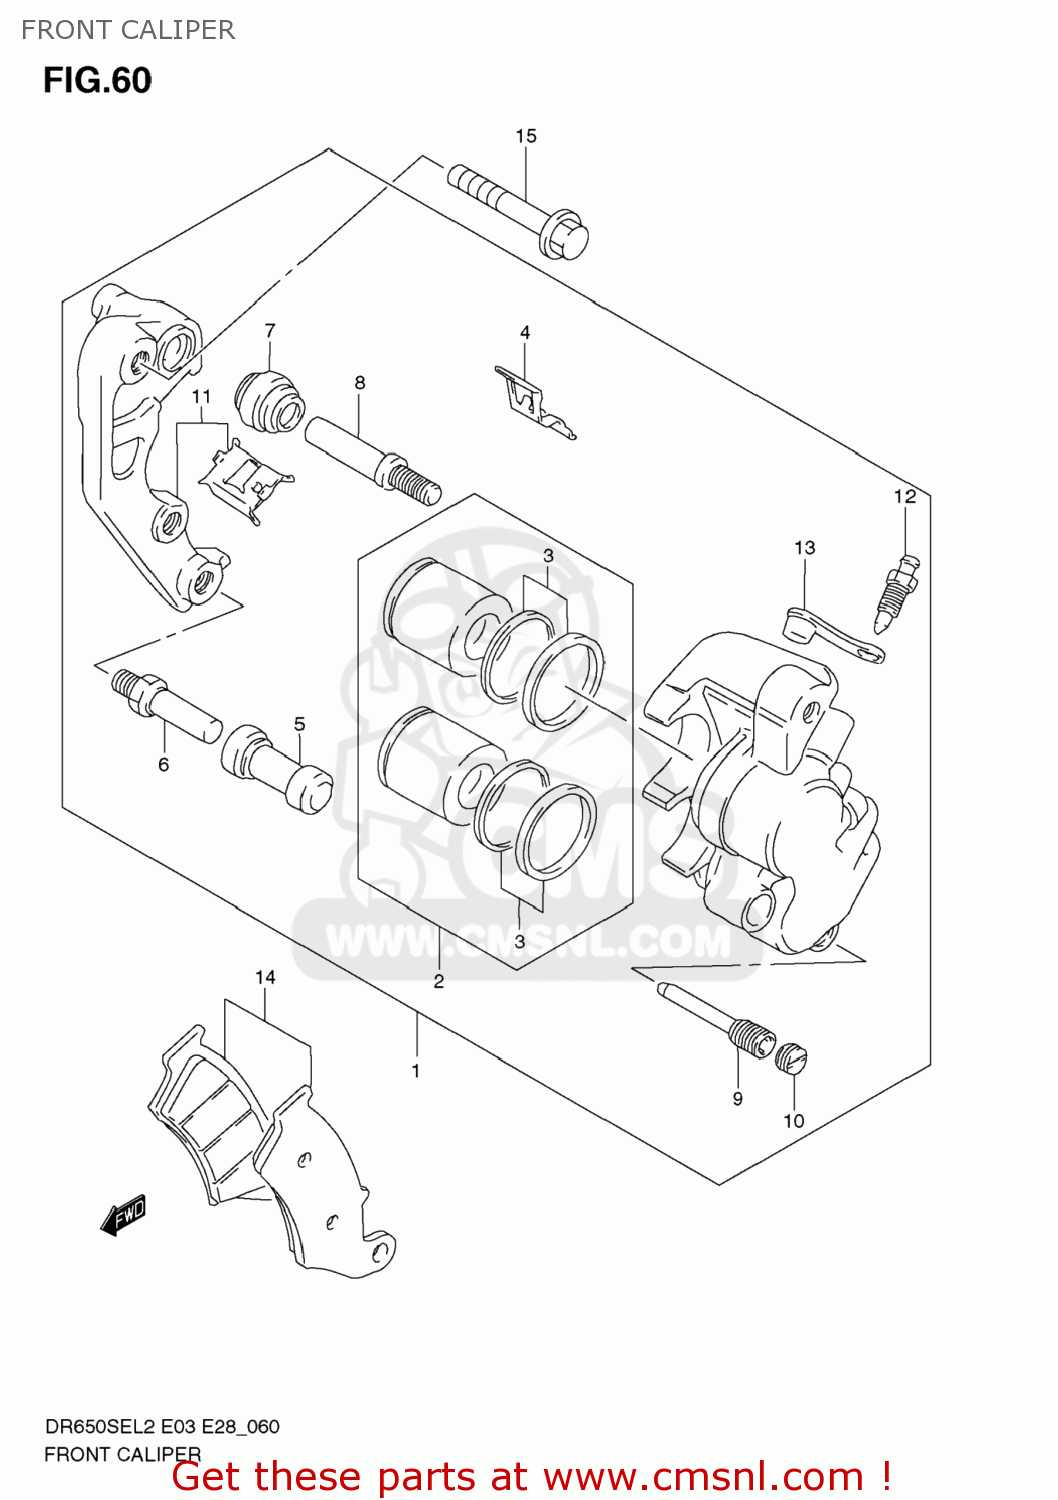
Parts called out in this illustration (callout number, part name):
1	CALIPER ASSY,FR,L
2	PISTON SET
3	SEAL SET,PISTON
4	SPRING,PAD
5	BOOT
6	PIN,BOLT
7	BOOT
8	PIN
9	PIN,HANGER
10	PLUG,PIN
11	BRACKET
12	BLEEDER
13	CAP,BLEEDER
14	PAD SET (NAS)
15	BOLT(8X40)
